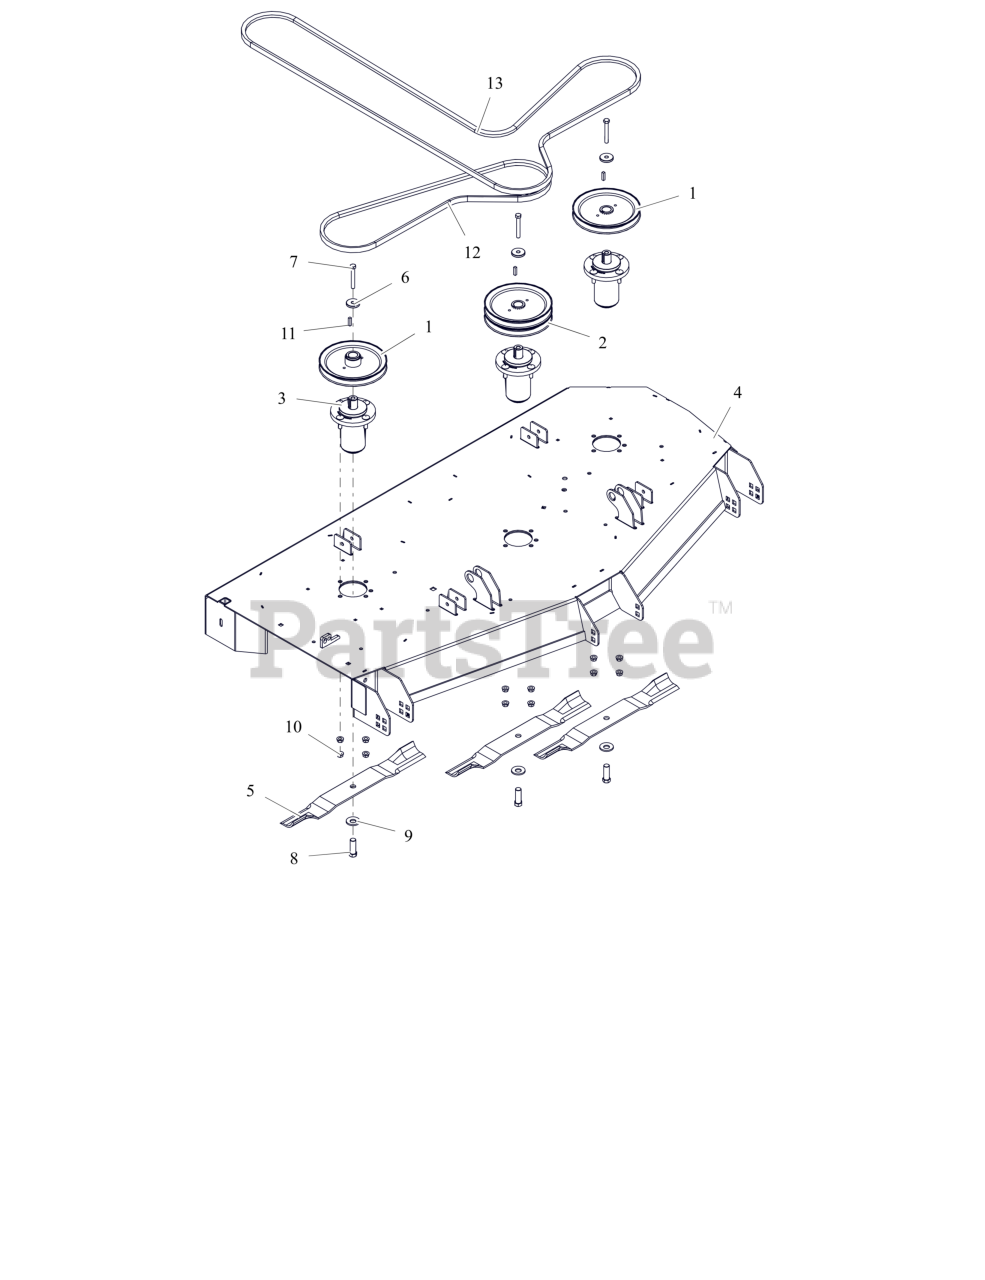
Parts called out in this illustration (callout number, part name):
1	PULLEY, V-7.50 OD X 1"ID
2	PULLEY, DOUBLE 1"X7.50"&7.50" (BLACK)
3	ASM, MAINT FREE ALUM SPINDLE
4	KIT, DECK - 60 W/DECALS - XF3
5	BLADE, 20.5"
6	RETAINER, SHEAVE
7	BLT, HEX .38-16X2.75 G8 ZCC
8	BLT, HEX .62-18X1.75 G8 ZCC
9	WSHR-BLVL .669X1.535X.138
10	NUT-LK-CTR-FLG .375-16 GF ZCC
11	KEY, SQ .25X.25X1.00 RC 40-50
12	V-BELT, B-COGGED
13	V-BELT, HB SECTION
